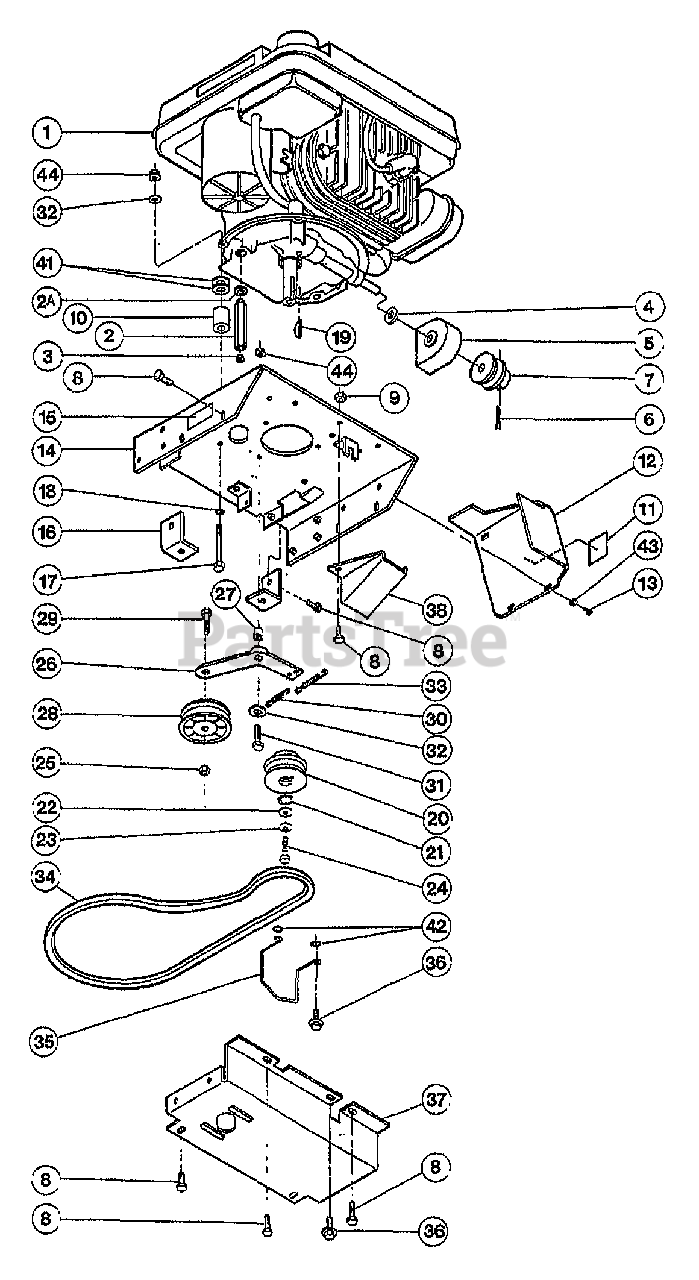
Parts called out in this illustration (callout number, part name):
1	ENGINE, TEC. 4HP, ELECTRIC START #TVS-105- 53629J
1	ENGINE, TEC. 4HP, STD. START #TVS-105-53630J
1	ENGINE, TEC. 3.5HP, STD. START #TVS-90-43637H
2	PLUG-OIL DRAIN
2A	GASKET-DRAIN PLUG
3	PLUG, ENGINE OIL DRAIN TUBE, 3/8
4	WASHER-FELT
5	ASSM-BELT GUIDE PTO
6	PIN-COTTER .188X1.5
7	PULLEY-ENG PTO MACHINE
8	SCR-HFLK 5/16-18X.62 G5ZP
9	NUT-HFLK 5/16-18 ZP
10	SPACER-1.125X.343X1.125
11	DECAL-HOT SURFACE
12	COVER-BELT W/DECAL (INCL. 11)
13	SCR-HW M10-32X.5 THRD ROLL
14	PLATE-DECK #40092P
15	DECAL-OIL DRAIN TUBE
16	SUPT-DECK #40094P
17	SCR HH 5/16-18X2.75 G8
18	WASHER-BELLEVILLE .328 ID
19	KEY-WOODRUFF .156X.625
20	PULLEY-CRANKSHAFT MACH
21	RING-RET INTERNAL
22	WASHER-1.25X.375X.1
23	WASHER-.994X.413X.145
24	SCR-HH 3/8-24X1.0 G5
25	NUT-HFLK 3/8-16
26	ARM-IDLER BLADE DR
27	BUSHING-.5X.31X.843 LG
28	PULLEY-FLAT IDLER (BLADE)
29	SCR-HFLK 3/8-16X1.50
30	SPRING-RETURN
31	SCR-HH 5/16-18X1.5 G5
32	WASHER-FLAT 5/16 SAE
33	SPRING-CABLE
34	BELT-CUTTER BAR
35	GUIDE-BELT
36	SCR-HXFL 5/16-18X.5 G5
37	COVER-BELT CUTTERBAR RED
38	GUARD-PAINTED 40133P
41	WASHER, FLAT, 1 1/8" OUTER DIA. x 11/32" INNER DIA.
42	WASHER-LK .312 EXT TOOTH
43	WASHER-#10 TYPE B PLN
44	NUT-TOP/LK 5/16-18
